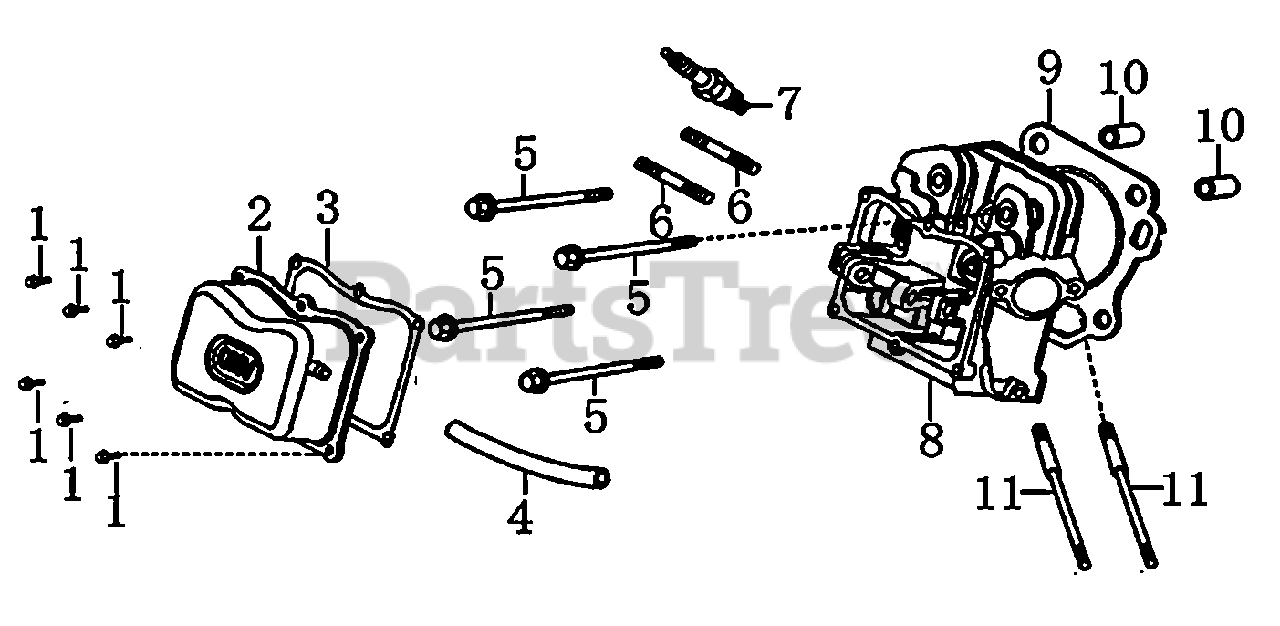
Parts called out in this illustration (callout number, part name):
1	BOLT, FLANGE
2	COVER, VALVE
3	GASKET, VALVE COVER
4	TUBE, BREATHER
5	BOLT, HEAD FLNG., 10X80
6	BOLT, STUD, EXHAUST
7	SPARK PLUG
8	HEAD, CYLINDER
9	GASKET, CYLINDER HEAD
10	PIN, DOWEL
11	BOLT, STUD, INTAKE
